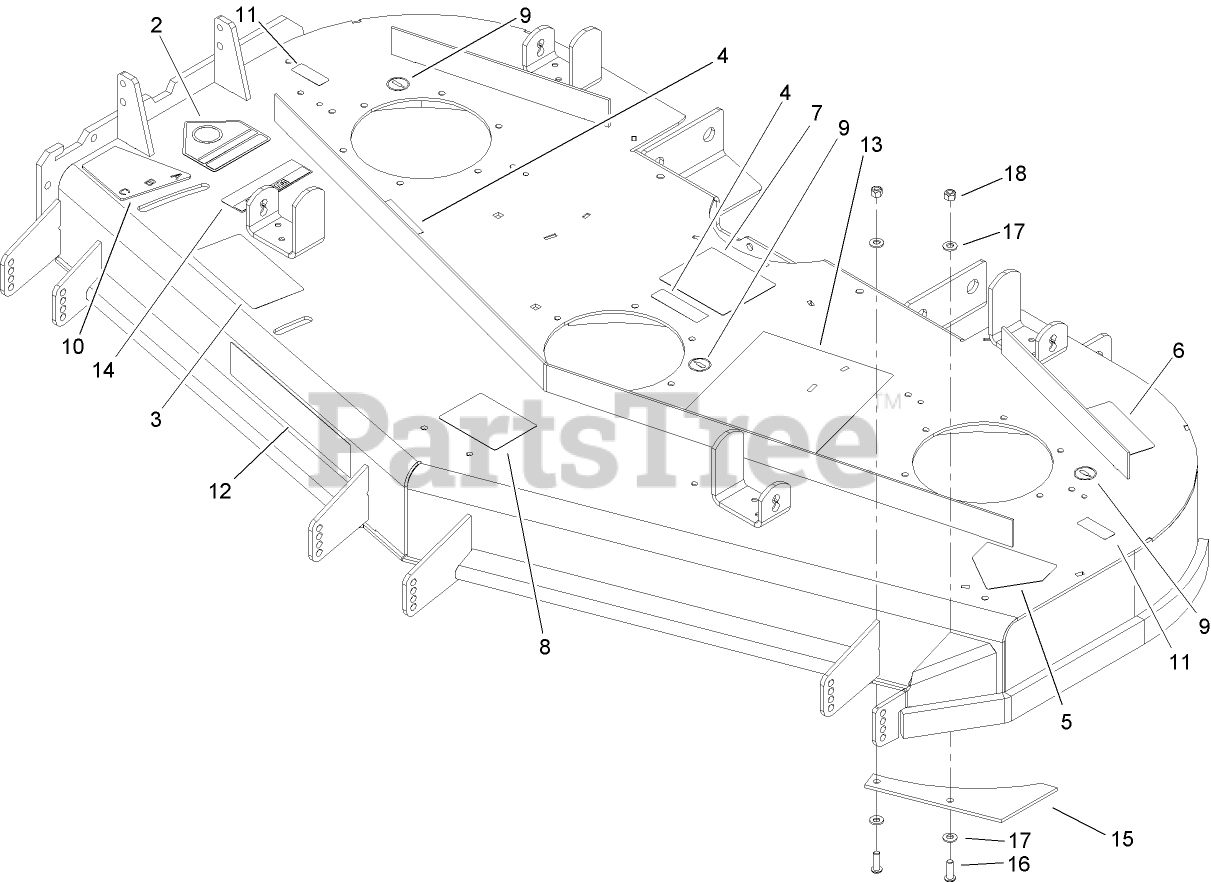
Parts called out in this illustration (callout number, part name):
2	DECAL-DANGER
3	DECAL-DANGER, THROWN OBJECT
4	DECAL-COVER, MISSING
5	DECAL-DANGER
6	DECAL-TORQUE
7	Decal-Routing, Belt
8	DECAL-SCALP, ANTI
9	DECAL-GREASE
10	DECAL-ADJUSTMENT, BAFFLE
11	Decal-Grease
13	Decal-Service, Check
14	DECAL-WARNING
15	PLATE-TURBO
16	SCREW-HSBH
17	WASHER-SPRING
18	NUT-LOCK, NI
